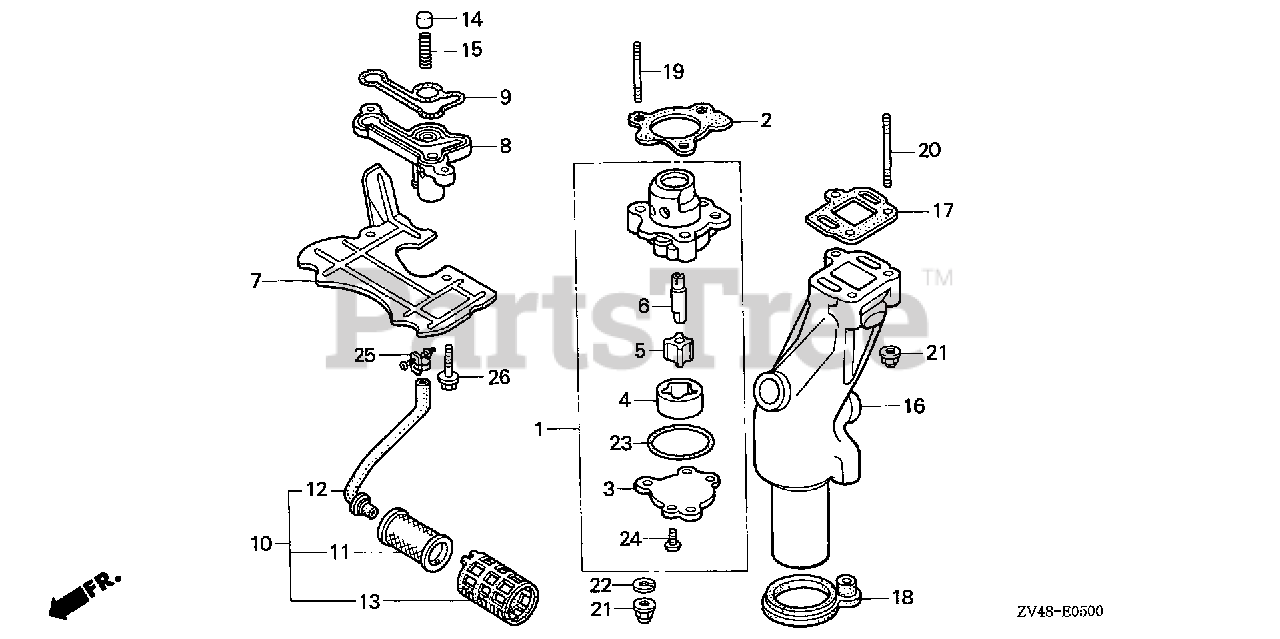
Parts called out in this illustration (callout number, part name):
1	PUMP ASSY., OIL
2	GASKET, PUMP BODY
3	COVER, OIL PUMP
4	ROTOR, OIL PUMP (OUTER)
5	ROTOR, OIL PUMP (INNER)
6	SHAFT, OIL PUMP
7	PLATE, DEFENSE
8	FLANGE, OIL FILTER
9	GASKET, OIL FILTER
10	FILTER ASSY., OIL
11	FILTER, OIL
13	HOLDER, OIL FILTER
14	VALVE, CHECK
15	SPRING, CHECK VALVE
16	PIPE, EX. *TBLACK* (BLACK)
17	GASKET, EX. PIPE
18	GROMMET, WATER TUBE
19	BOLT, STUD (6X39)
20	BOLT, STUD (6X42)
21	NUT, CAP (6MM)
22	WASHER, SPRING (6MM)
23	O-RING, PUMP COVER
24	SCREW, PAN (5X8)
25	CLAMP, TUBE (D10.5)
26	BOLT, FLANGE (6X22)
